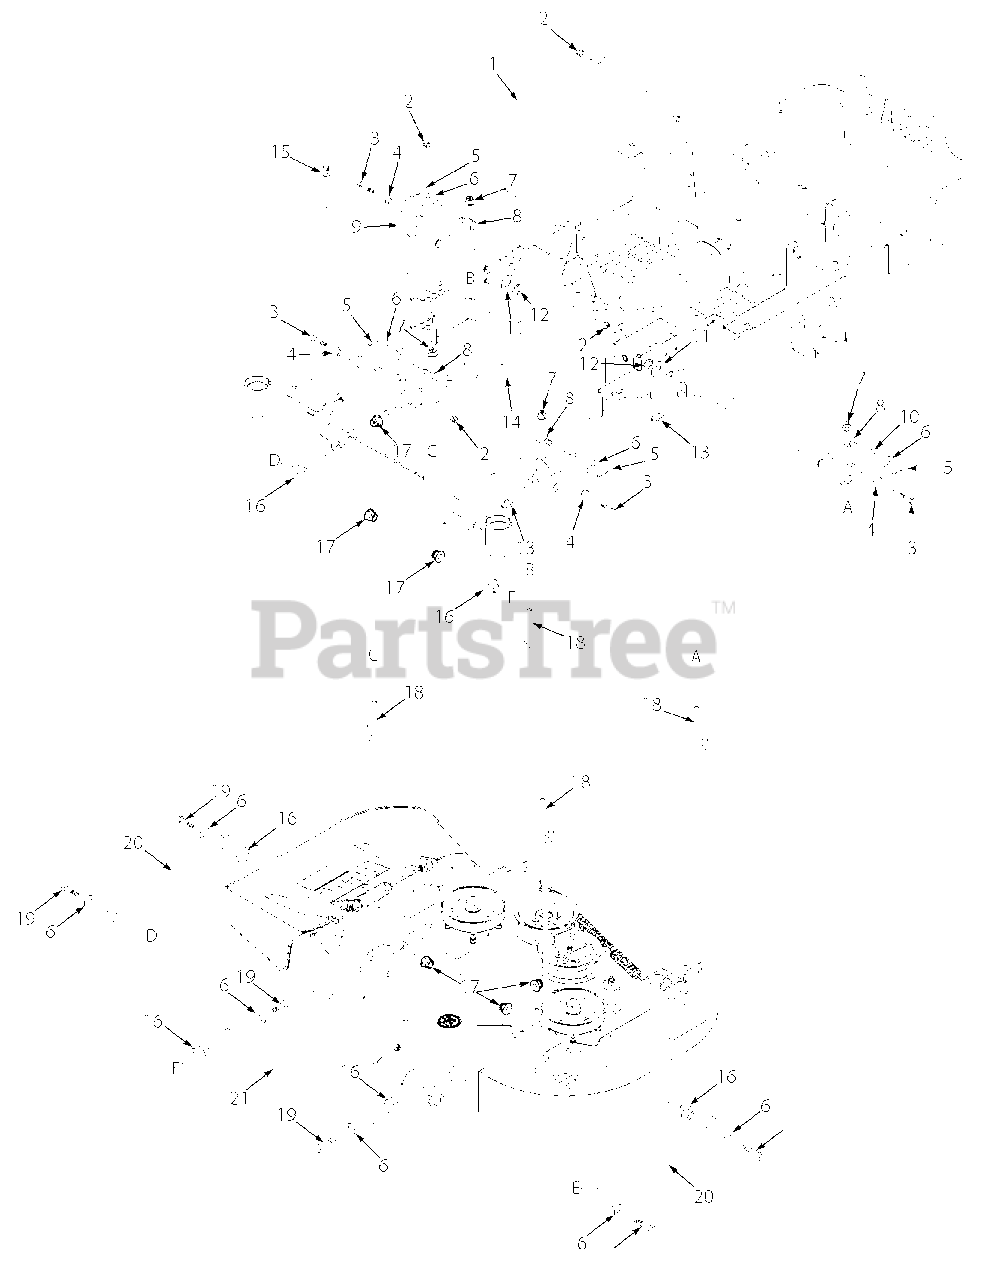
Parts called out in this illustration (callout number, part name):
1	Link, Deck Lift - LH
2	Nut, 3/8-16 Elastic Stop
3	Bolt, Hex Head 3/8-16 x 1-1/4"
4	Bushing
5	Cotter Pin, 3/16 x 1"
6	Flatwasher, 1/2-.531 x 1.062 x .095
7	Nut, 1/2-13 Elastic Stop
8	Joint, Swivel
9	Lift Bellcrank Weldment, RH
10	Lift Bellcrank Weldment, LH
11	Flatwasher, 3/4-.769 x 1.250 x .0598
12	Retaining Ring, .750 "E"
13	Grease Fitting, 1/4-28 Self Tap
14	Link, Deck Lift - RH
15	Pin Assembly, Deck Height
16	Bushing, Deck latch
17	Nut, 1/2-13 Elastic Stop
18	Rod, Deck lift
19	Bolt, Hex Head 1/2-13 x 1-3/4
20	Pull Arm, Deck
21	Lateral Link
